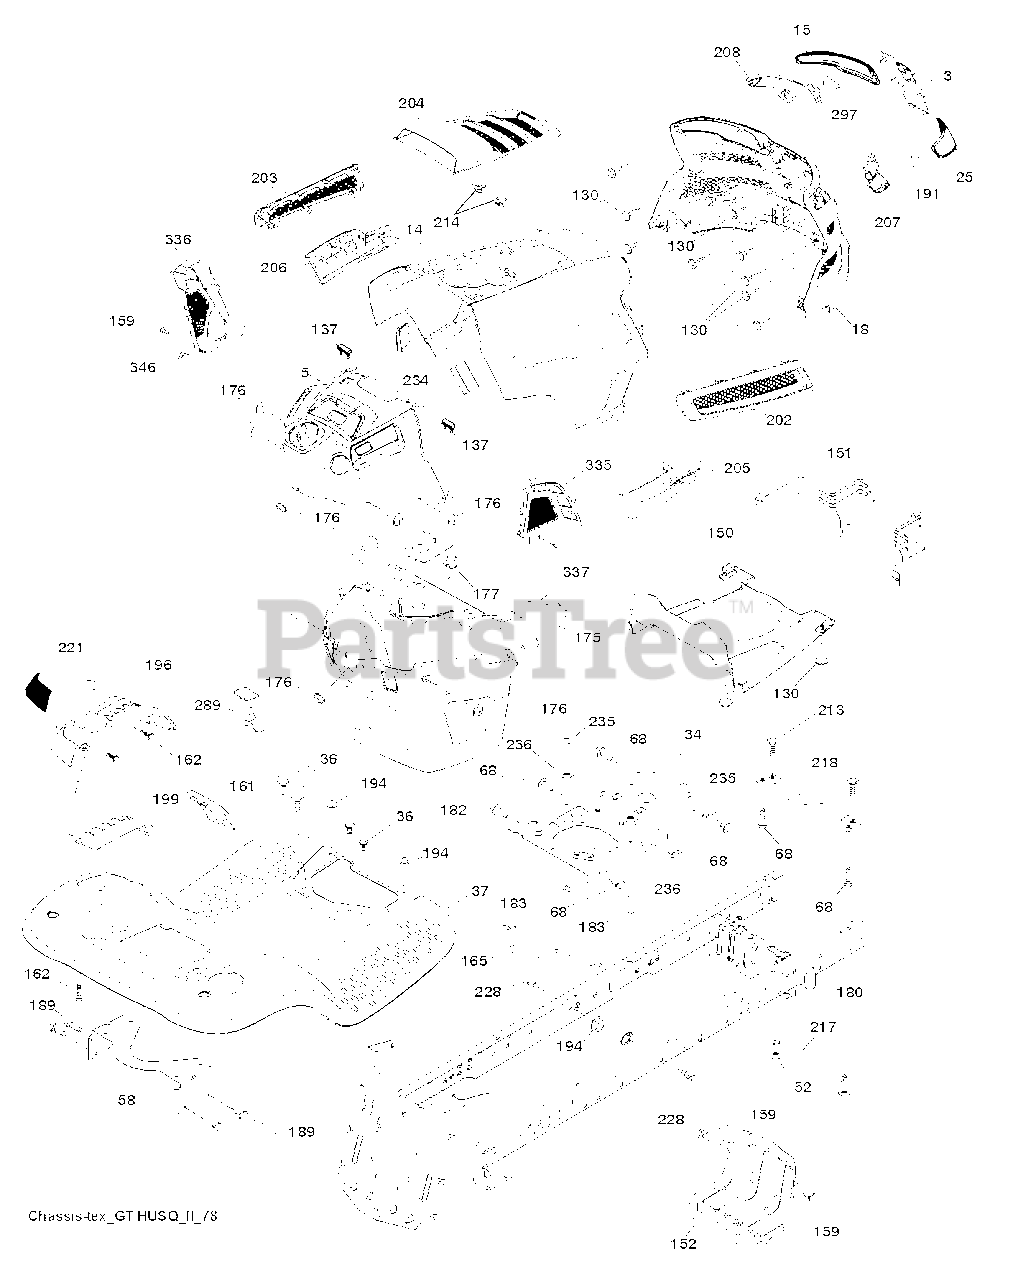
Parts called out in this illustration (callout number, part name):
3	APPLIQUE.SUBASM.GT.HUSQ.II
5	DASH.UPP.GT2.SM.PTO.MCHOKE
14	HOOD.ASM.HUSQVARNA.GT.TEX.ORAN
15	LENS.HEADLIGHT.LH.GTII.2011
18	GRILLE.SUBASM.GT.HUSQ.II
25	LENS.HEADLIGHT.RH.GTII.2011
34	PLATE.ENGINE.WELDED.CHASSIS
36	SCREW 5/16"
37	FENDER.PNT.TX.GT.CH/FW/DL.HUSQ
52	LOCKNUT
58	BRKT.SUPPORT.FNDR/TANK
68	SCREW LT
130	SCREW.#10 X 0.750.BOS
137	BUMPER DASH
150	AIR.DUCT.GTV.BLACK
151	BRACKET.PIVOT.HOOD.GT.HUSQ.II
152	SHIELD.BROWNING.PNT.GT.V2
159	Hex Washer Head Screw, 3/8-16 X 3/4 Thread Rolling
161	CONSOLE.WINDOW.FUEL.HUSQ.GT
162	SCREW.HI-LO.CONSOLE
165	SUPPORT.TANK.REAR.W/TEX
175	PLATE.CROSSMEMBER.HUSQ
176	SCREW.#10-24X5/8.RN.QU
177	BUSHING, STEERING
180	CHASSIS.GT.SLOPED.DRAWBAR.
182	DASH.LOWER.COMMON.12V.ADAPTOR
183	BOLT.5/16-18X1-1/4 FULL.THREAD
189	SCREW
191	INSERT.REFLECTIVE.RH.HUSQ.GTII
194	NUT LOCK HEX FLANGE 5/16-18
196	SUBASM.CONSOLE.HUSQ.GT.DECKLFT
199	PLATE.DECK.LIFT.HUSQVARNA.GT
202	VENT.SIDE.RH.GT.HUSQ.II.
203	VENT.SIDE.LH.GT.HUSQ.II.498
204	VENT.TOP.HUSQ.GT2
205	SIDE.TRIM.RH.GT.HUSQ.II
206	SIDE.TRIM.LH.GT.HUSQ.II.GRAY
207	BEZEL LIGHT.RH.GT.II.MYLAR
208	BEZEL LIGHT.LH.GT.II.MYLAR
213	BOLT
214	CLIP.RETAINER.TINNER.
217	ROD.PIVOT.HOOD
218	X-PIECE.HOOD.STOP.NON/
221	REFLECTOR.LH.TEX GT HU
228	STUD.FASTNER.W/ANTI-ROTATE
234	BUMPER.HOOD.TEX.HUSQVARNA
235	SPACER FENDER
236	NUT.CENTERLOCK.5/16-
289	PLUG.N/CRUISE.COMMON.YT/GT.BLK
297	INSERT.REFLECTIVE.LH.HUSQ.GTII
335	COVER.RH.CLOSE.OUT.BLACK
336	COVER-LH.LOWER.DASH.GT2.BLACK
337	CLIP.XMAS.TREE.ITW.2622-00
346	CLIP,INSULATOR
